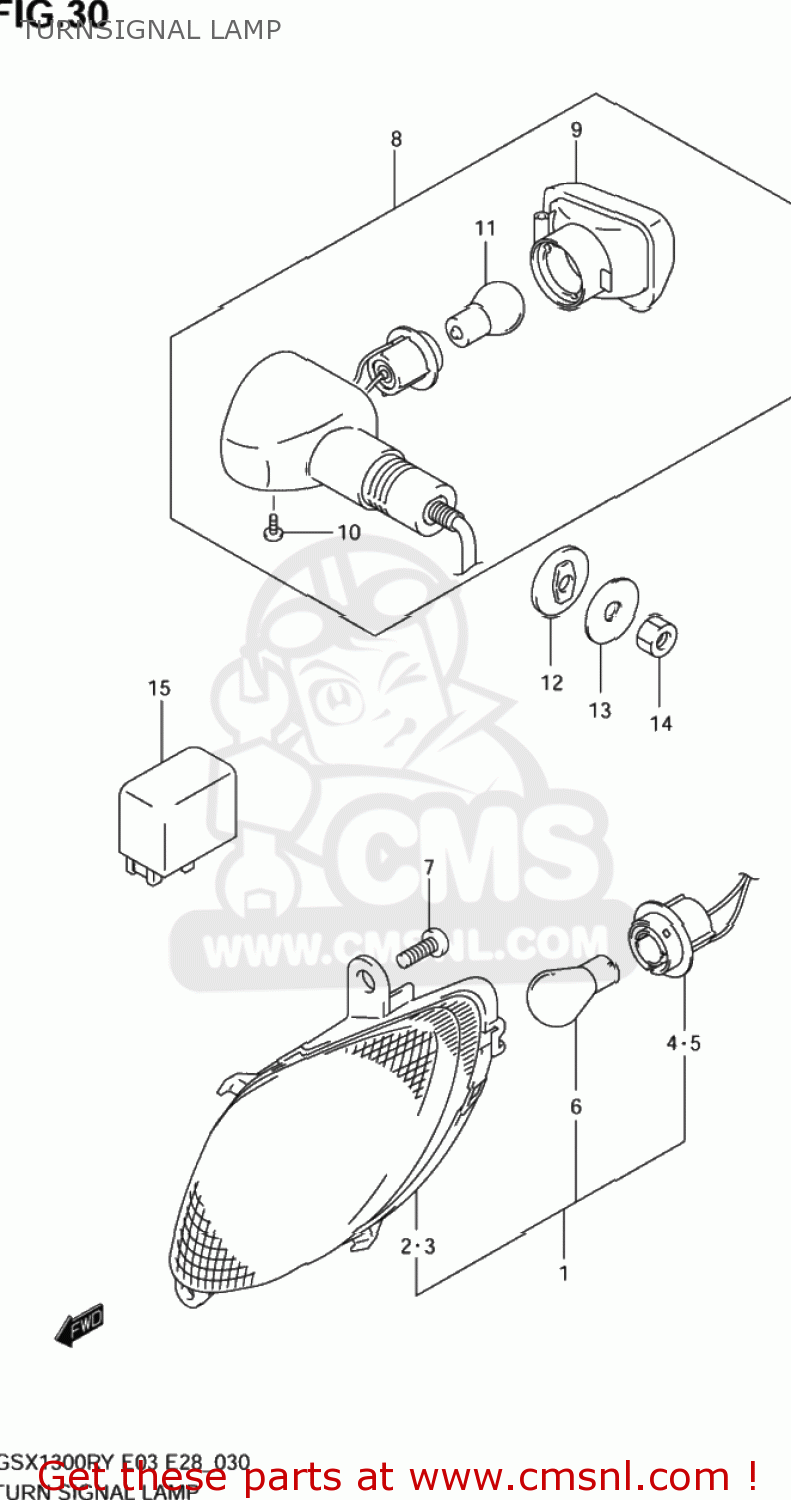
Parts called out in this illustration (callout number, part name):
1	LAMP ASSY,FR TURN SIGNAL,R
2	LAMP UNIT,R
3	LAMP UNIT,L
4	SOCKET & CORD,R
5	SOCKET & CORD,L
6	BULB(12V21W)
7	SCREW
8	LAMP ASSY,RR TURNSIGNAL,R
9	LAMP UNIT
10	SCREW
11	BULB(12V21W)
12	SPACER,RR TURNSIGNAL
13	WASHER(10.5X30X2.3)
14	NUT
15	RELAY ASSY,TURNSIGNAL LAMP
